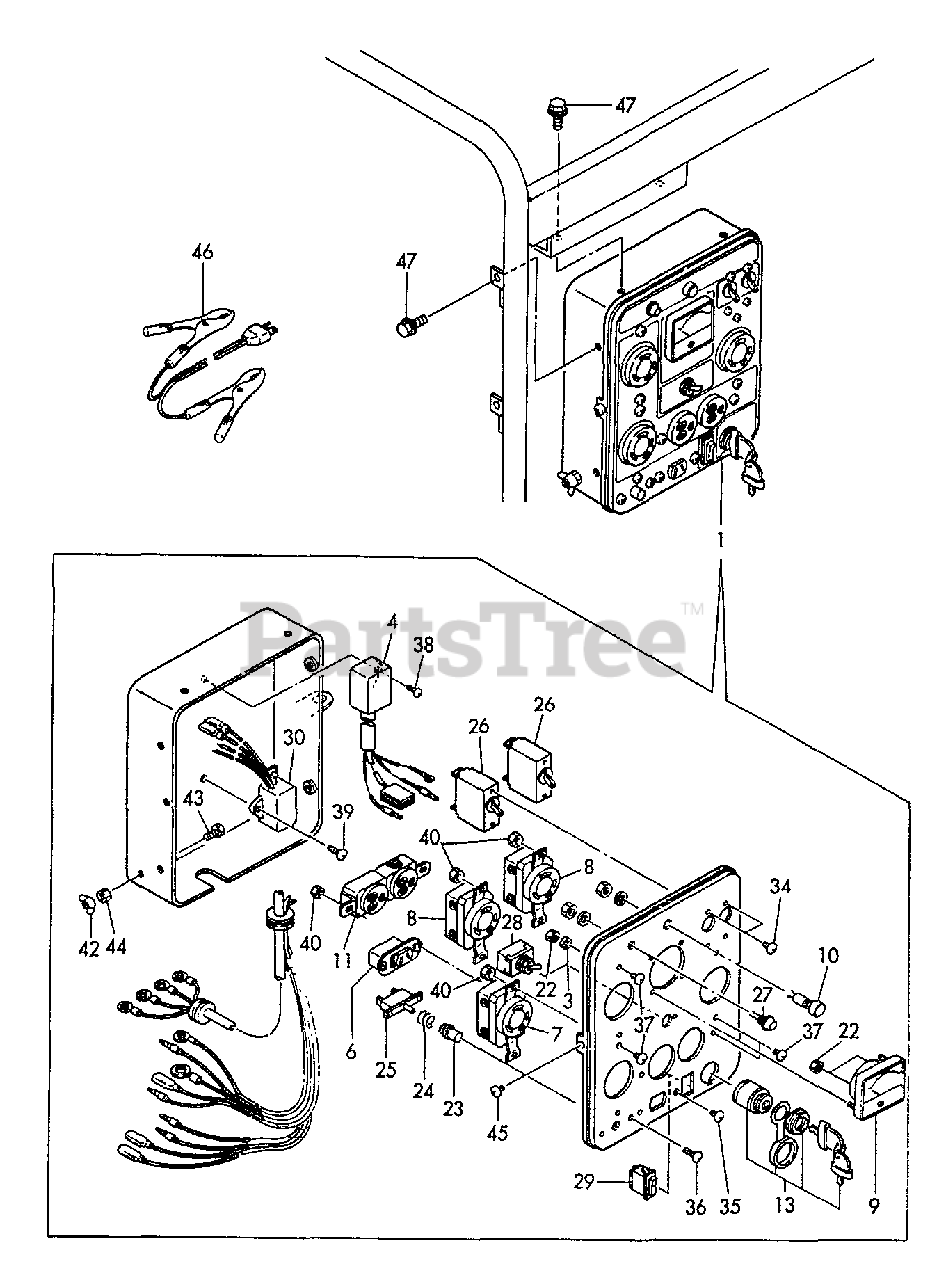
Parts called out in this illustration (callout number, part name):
1	PANEL BOX ASSY
3	LOCKWASHER
4	SENSOR, OIL
6	DC CONNECT
7	CONNECTOR
8	CONNECTOR
9	METER, VOLTAGE - 300V
10	LAMP, PILOT
11	AC CONNECT
13	KEY SWITCH ASSY
22	NUT - 3
23	CAP, BREAKER
24	SPRING, BREAKER
25	BREAKER
26	AC BREAKER
27	LAMP, OIL ALERT
28	SWITCH
29	SWITCH
30	UNIT, SLOW-DOWN
34	SCREW - 3X6
35	SCREW - 3X6
36	SCREW - 3X14
37	SCREW - 4X6
38	SCREW - 5X10
39	SCREW - 5X10
40	NUT - 4
42	WINGNUT - 6
43	BOLT - 6X16 -- PLATED
44	LOCKNUT - 6 -- PLATED
45	SCREW - 4X6
47	BOLT - 6X8 -- PLATED
